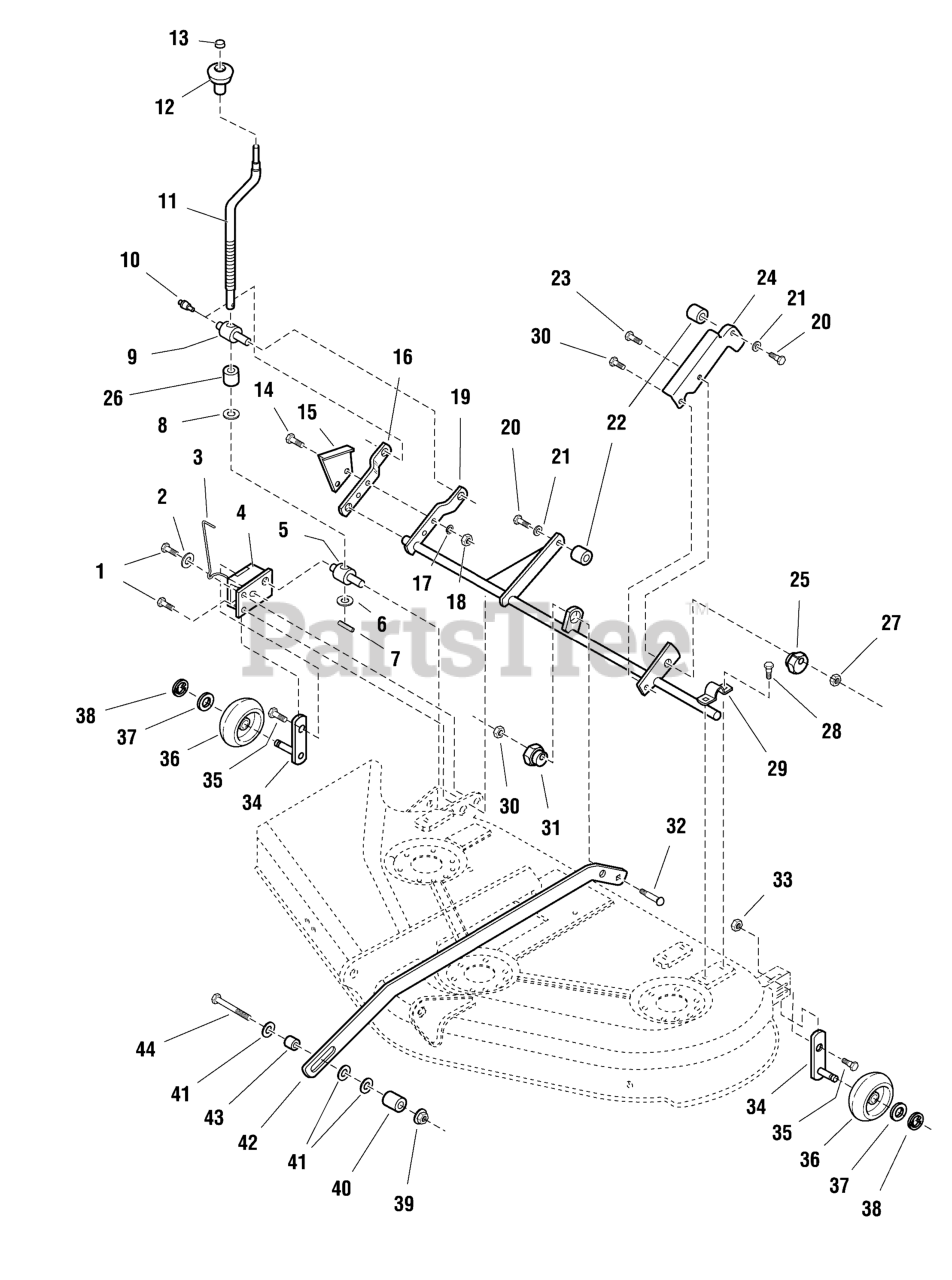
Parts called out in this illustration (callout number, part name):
1	CAPSCREW, Hex Washer Head Taptite, 5/16-18 x 1-1/4
2	WASHER, 5/16
3	ROD, Indicator Height of Cut
4	PLATE & BRACKET ASSEMBLY, Guage Wheel
5	TRUNNION, 1-1/4
6	WASHER, Detent
7	PIN, Spring
8	WASHER, 9/16
9	TRUNNION, 1-1/4
10	FITTING, Lube
11	CRANK, Height Adjustment
12	KNOB, Spinner, Soft
13	NUT, Push
14	CAPSCREW, Hex Head, 5/16-18 x 1 1/4
15	BRACKET, Height of Cut
16	ARM, Rear
17	LOCKWASHER, Spring, 5/16
18	NUT, Hex, 5/16-18
19	ARM ASSEMBLY, Roller Bar 44"
20	CAPSCREW, Hex Head, 3/8-16 x 1, G5
21	LOCKWASHER, Spring, 3/8
22	SPACER, Support
23	CARRIAGE BOLT, 5/16-18 x 1-1/4, G5
24	ARM, Rear Adjustable
25	CAM, Eccentric, Hex
26	SPACER, .66 X 7/8 X 1 1/4
27	NUT, Hex Flange Collar Lock, 5/16-18
28	CAPSCREW, Hex Washer Head Taptite, 5/16-18 x 3/4
29	STRAP
30	NUT, Hex Flange, 3/8-16
31	NUT, Hex Adjusting, 11/16
32	BOLT, Carriage, Short Neck, 3/8-16 x 1-1/2
33	NUT, Hex Flange Toplock 1/4-20
34	SHAFT & BAR ASSEMBLY, Roller Fixed Arm
35	CAPSCREW, Hex Head, 1/4-20 x 3/4, G5
36	WHEEL, Roller
37	WASHER, 1/2
38	E-RING, Retaining Extenstion
39	NUT, Hex Flange, 3/8-16, Two Way Lock
41	WASHER, 3/8
42	ARM, Pitch 44"
44	CAPSCREW, 3/8-16 x 2
